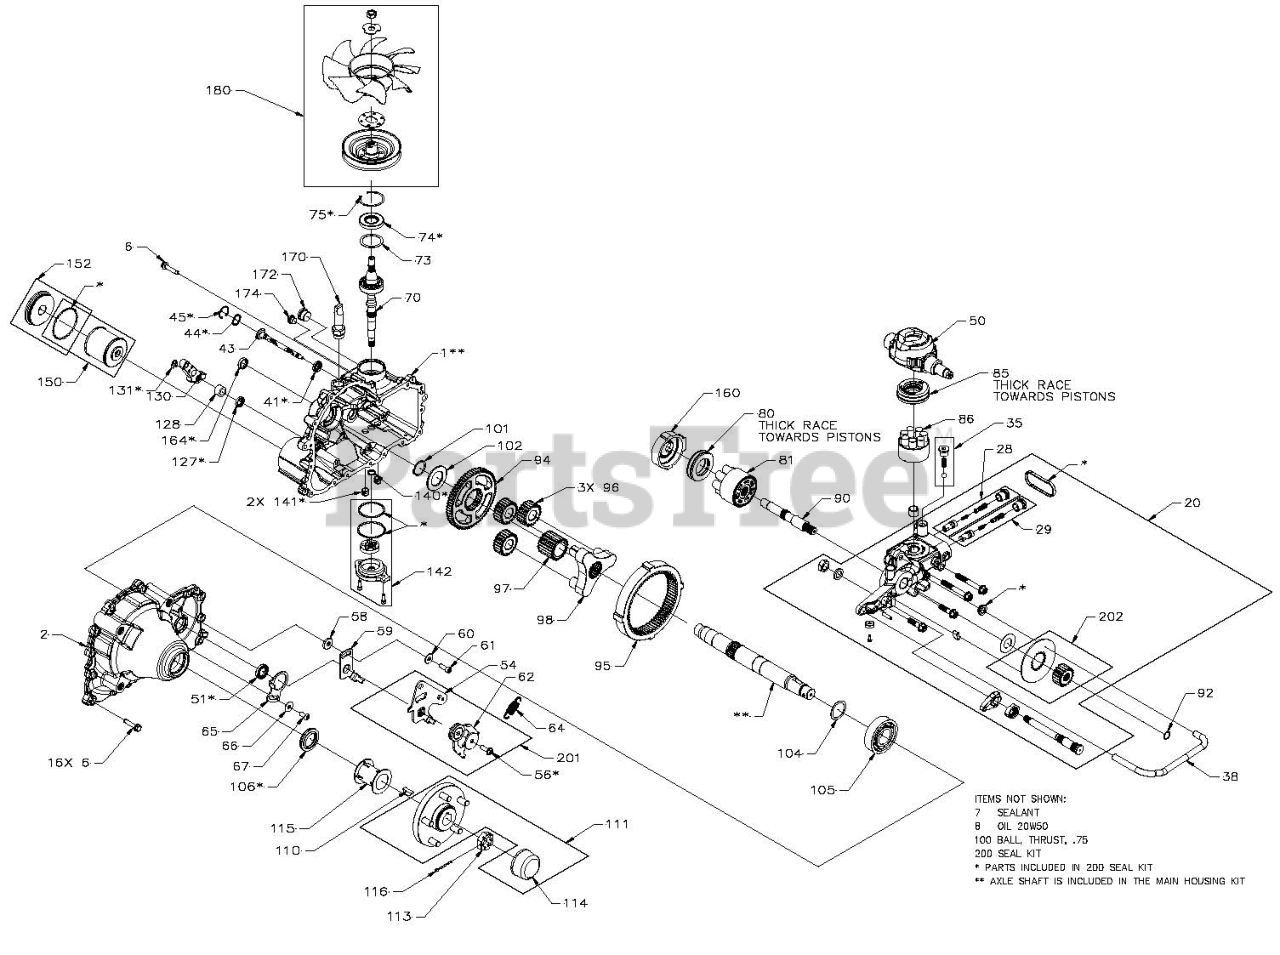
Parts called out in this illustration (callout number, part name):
1	KIT, HOUSING, MAIN, RH
2	KIT, HOUSING, SIDE, RH
7	SEALANT TUBE 10.1OZ.
8	KIT, HYDRO OIL ZT5400
20	CENTER SECTION KIT R(03935200)
28	HG SHOCK VALVE KIT
29	HG SHOCK VALVE KIT
35	HG CHARGE RELIEF VALVE KIT
38	TUBE, FILTER, RH
41	SEAL, LIP 12 X 24 X 5 TC
43	ASSEMBLY, ACTUATOR BYPASS
44	SPRING, WAVE
50	SWASHPLATE, 16CC, MACHINED
54	ARM, CONTROL, RH
56	TWHCS 5/16-24 X 1.00
59	ARM, NEUTRAL RIGHT
61	SHCS 5/16-24X1 PATCH
62	ARM, SCISSOR
64	RTN SPRING HG 51605
65	PLATE, STOP, RH
70	INPUT SHAFT HG 71941
74	SEAL, LIP 25 X 52 X 7 TC
75	RING, RETAINING, INTERNAL
80	BRG, THRUST (21) 42X68X16, PLASTIC CAGE
81	KIT, MOTOR BLOCK
86	KIT, BLOCK, 16CC CYLINDER
90	SHAFT, MOTOR
92	RING, RET 62 EXT
98	CARRIER
100	BALL, .75
102	SPACER, THRUST, AXLE
105	BEARING,BALL 35 X 80 X 21 6307
106	HG SEAL LIP 1.375X2.062X.250
110	KEY, WOODRUFF 5/16 X 1
111	HG 5 BOLT HUB KIT
113	HG HEX NUT 1-20 SLOTED
114	HG AXLE HUB CAP - ZT5400
116	PIN, COTTER 9/64 X 2 EXTENDED
130	BRAKE ARM HG 53018
131	CLIP,BRAKE ARM HYDROGEAR 52027
140	SEAL, .50 X .69 X .09 VC
141	TUBE, PUSH O-RING
142	CHARGE COVER KIT
150	FILTER,HYD OIL W/ORING ZT-54OO
152	HG FILTER PLUG KIT
160	PLATE, MOTOR, SWASH
164	SEAL, PLUG
170	FITTING, 7/8-14 SAE, .625 BEADED
172	PLUG, 7/8-14, METAL
174	PLUG, 9/16-18, METAL
180	PULLEY/FAN KIT HG 71906
200	SEAL KIT HG 71945
201	KIT, RTN, BIDIRECTIONAL
202	KIT, BRAKE ROTOR, GEAR
